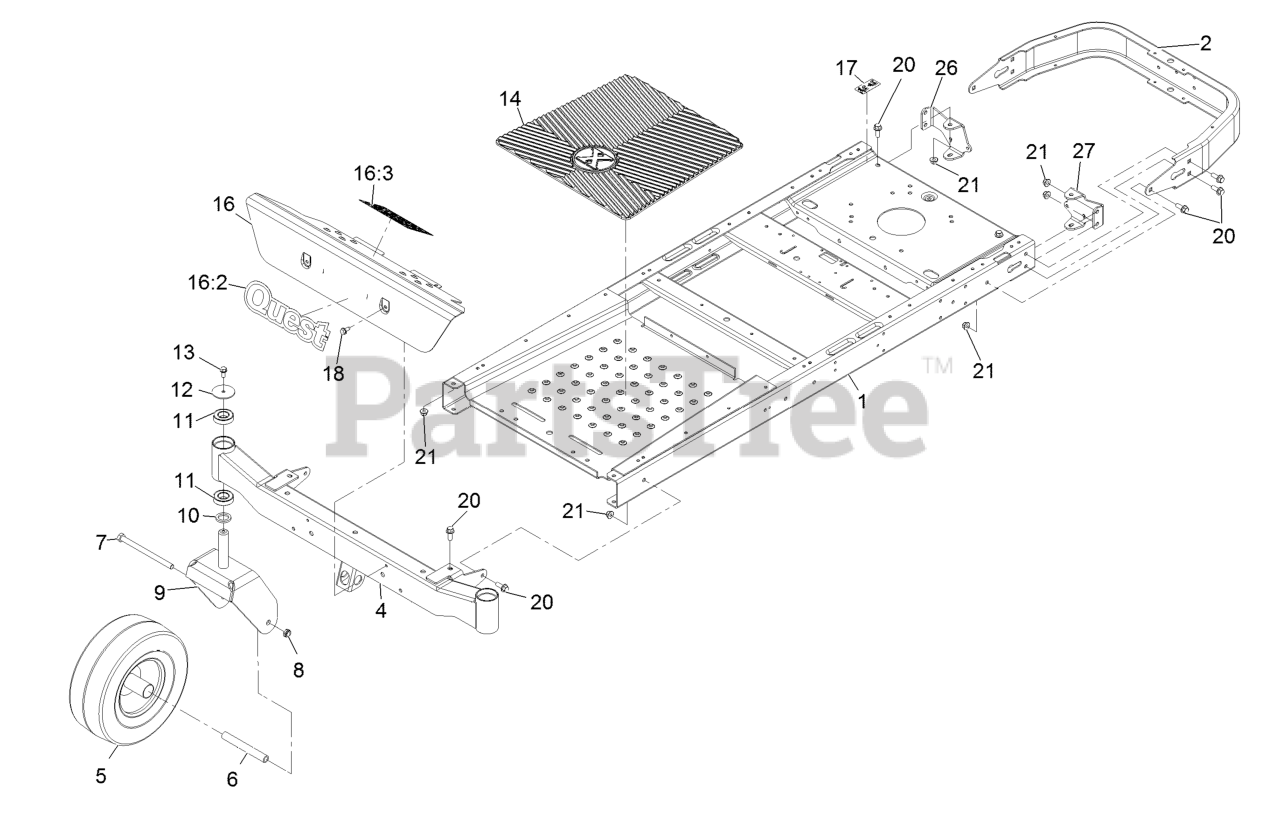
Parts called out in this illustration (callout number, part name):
2	BUMPER-REAR (WIDE)
4	AXLE-FRONT (WIDE)
5	13 INCH WHEEL AND TIRE AS
6	SPANNER
7	WASHER-LOCK
8	NUT-HEX
9	FORK-CASTER
10	WASHER-THRUST
11	BEARING-BALL
13	SCREW-HHF
14	MAT-FLOOR
16	FOOTREST SERVICE ASM
17	DECAL-BYPASS
18	Screw-HWH 5/16-18 X 3/4 Tf
20	SCREW-HHF 3/8-16 X 1
21	NUT-HF, NI
26	MOUNT-HYDRO, REAR (RH)
27	MOUNT-HYDRO, REAR (LH)
